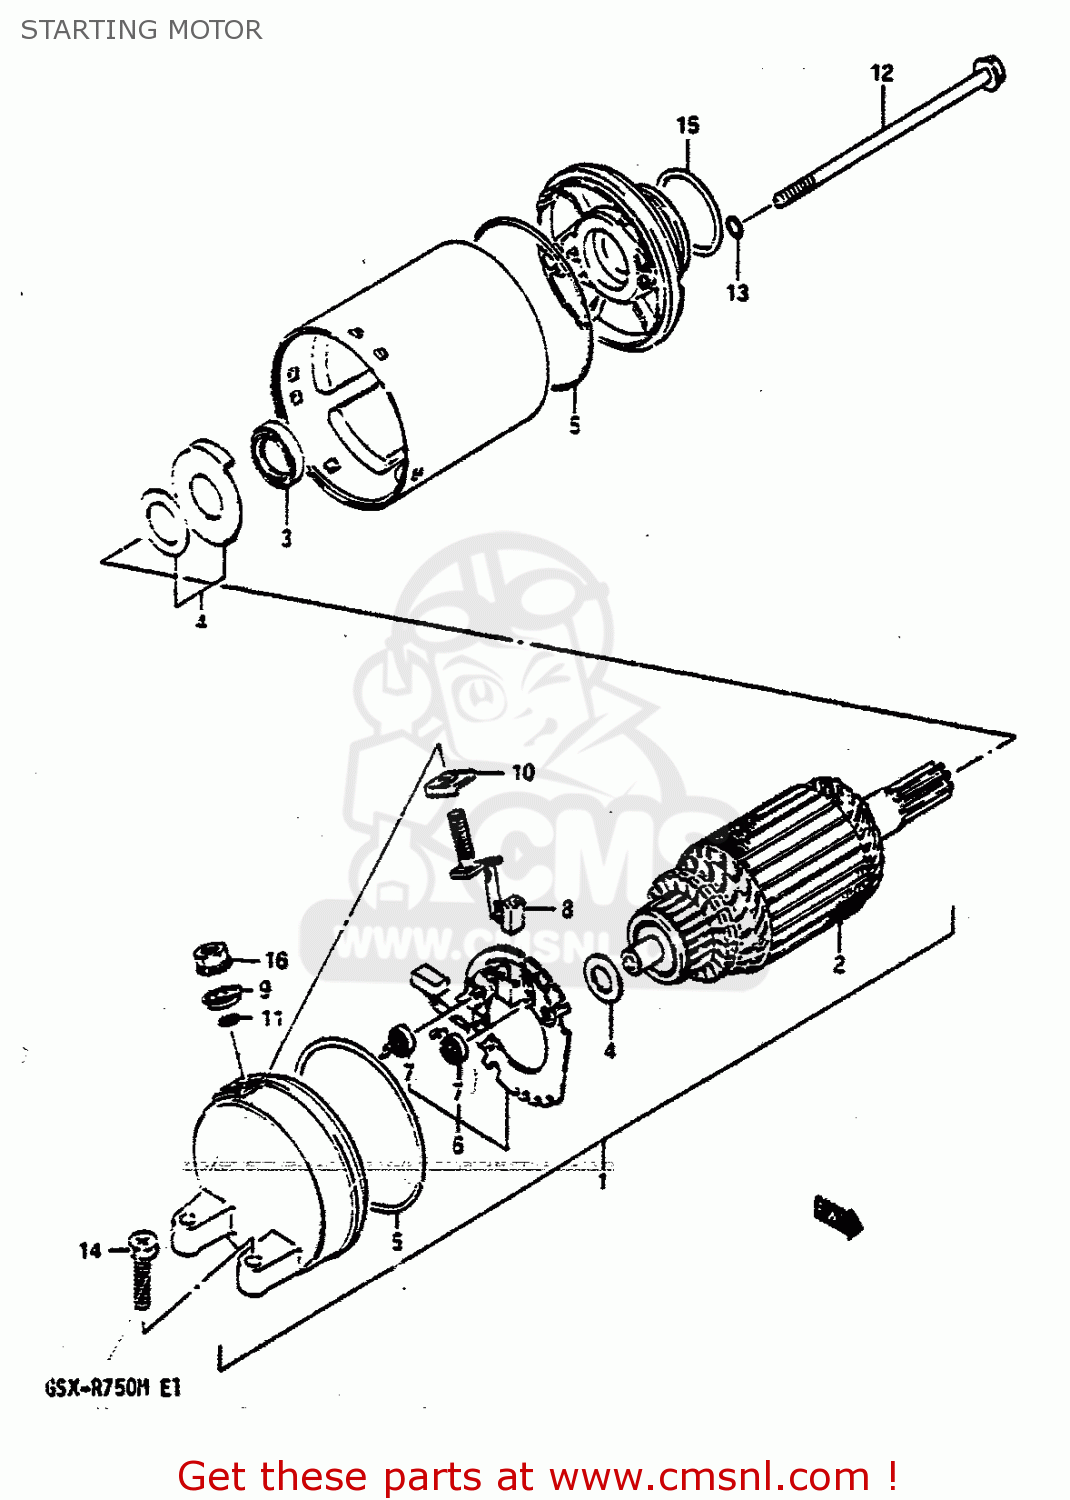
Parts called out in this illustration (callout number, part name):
1	MOTOR ASSEMBLY,STARTING
2	ARMATURE
3	SEAL,OIL
4	SHIM SET,STARTING MOTOR
5	O RING
6	HOLDER,BRUSH
7	SPRING
8	BRUSH SUB ASSY,STARTING MOTOR
9	BUSHING
10	BUSH,B
11	O RING
12	BOLT
13	O RING
14	SCREW (6X25)
15	O RING(D:3,ID:24.5)
16	NUT
